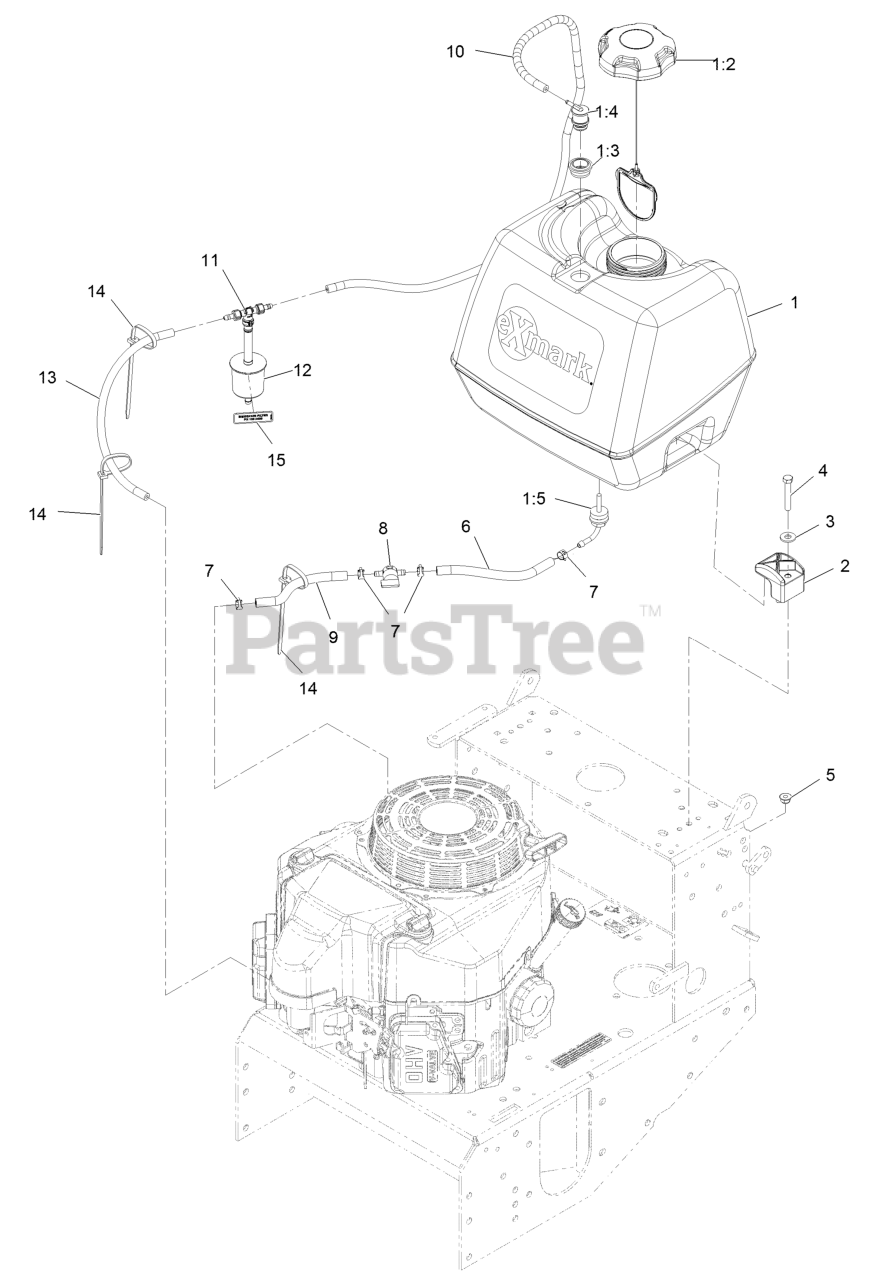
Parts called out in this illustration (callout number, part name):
1	ASM, FUEL TANK
1:3	GROMMET
1:4	VALVE-VENT, FUEL
1:5	FITTING-FUEL, BULKHEAD
3	WASHER-FLAT
4	SCREW-HH
5	NUT-HF, NI
6	HOSE-FUEL
7	CLAMP-HOSE
8	VALVE-FUEL
9	HOSE-FUEL
10	HOSE-EMISSIONS
11	TEE AND CHECK
12	FILTER-FUEL
13	HOSE-FUEL
14	TIE-PLASTIC
15	DECAL-FILTER, EMISSIONS
16	Pn 41019-1055 Filter W/6In Fuel Line
